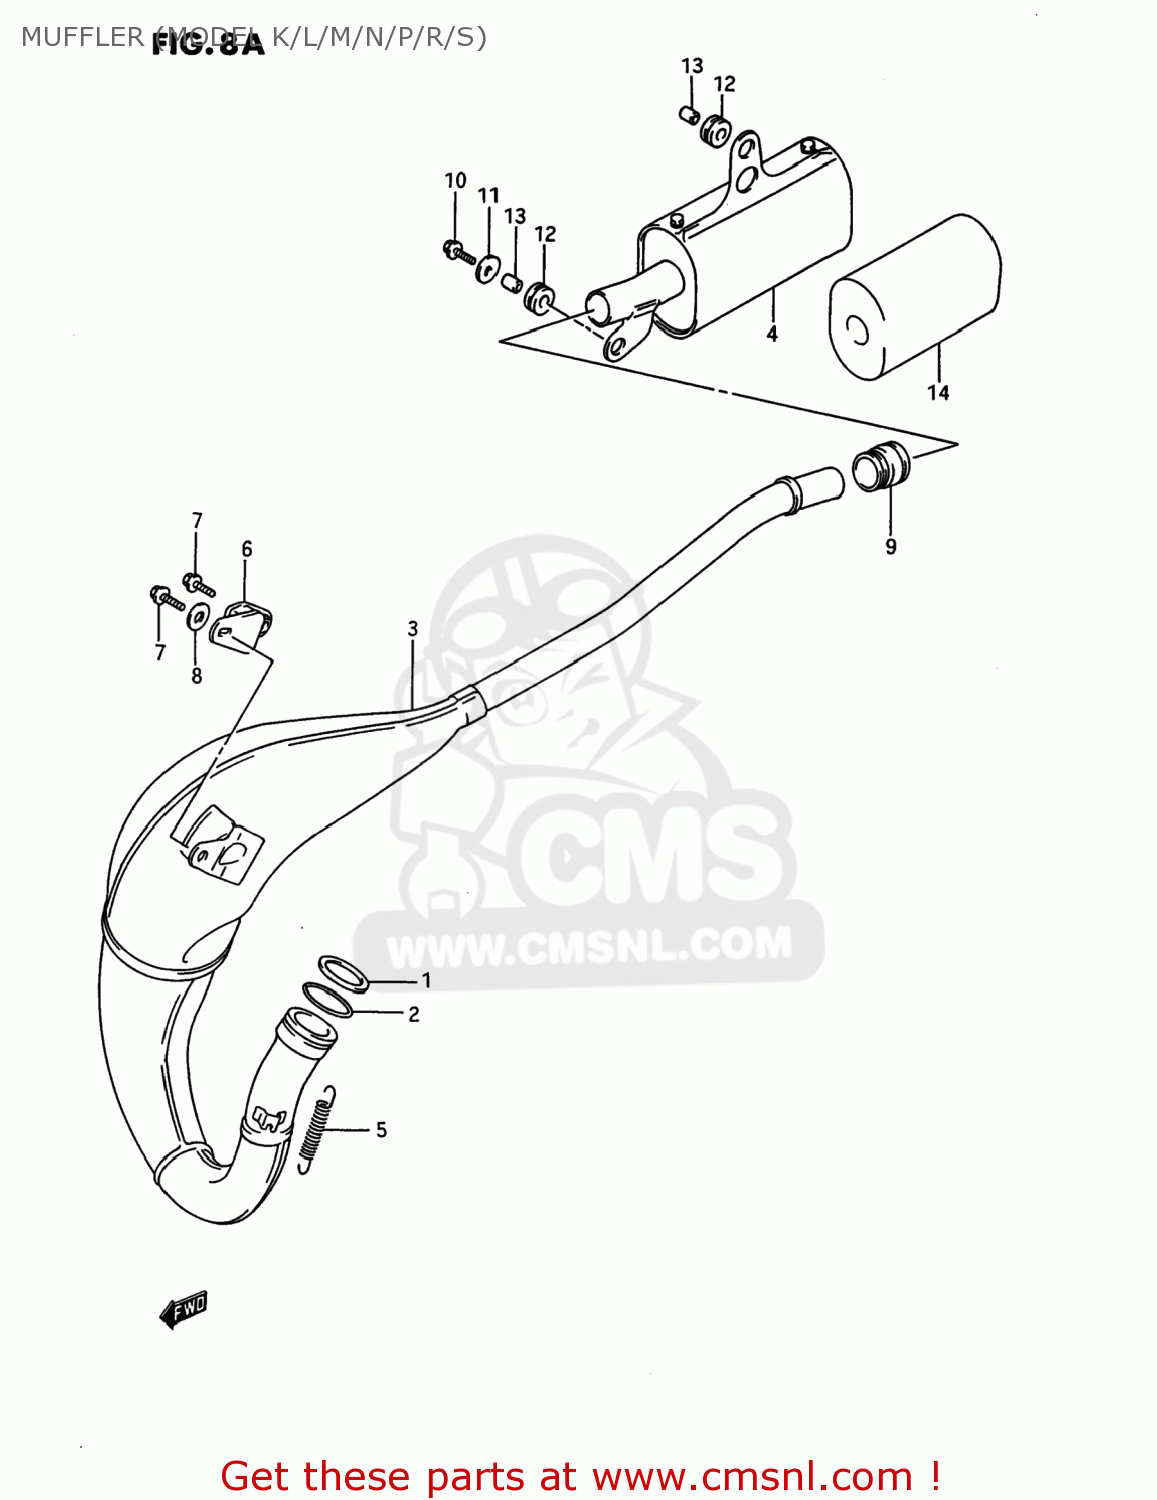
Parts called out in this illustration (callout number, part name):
1	WASHER,EXH FLANGE
2	O RING,EXH FLANGE
3	BODY,MUFFLER
4	BODY,MUFFLER,SECOND
5	SPRING
6	DAMPER,MUFFLER SUPPORT
7	BOLT
8	WASHER(6.5X16X1.2)
9	CONNECTOR,MUFFLER
10	SCREW
11	WASHER (6.5X20X1.2)
12	CUSHION
13	SPACER
14	SILENCER,MUFFL
